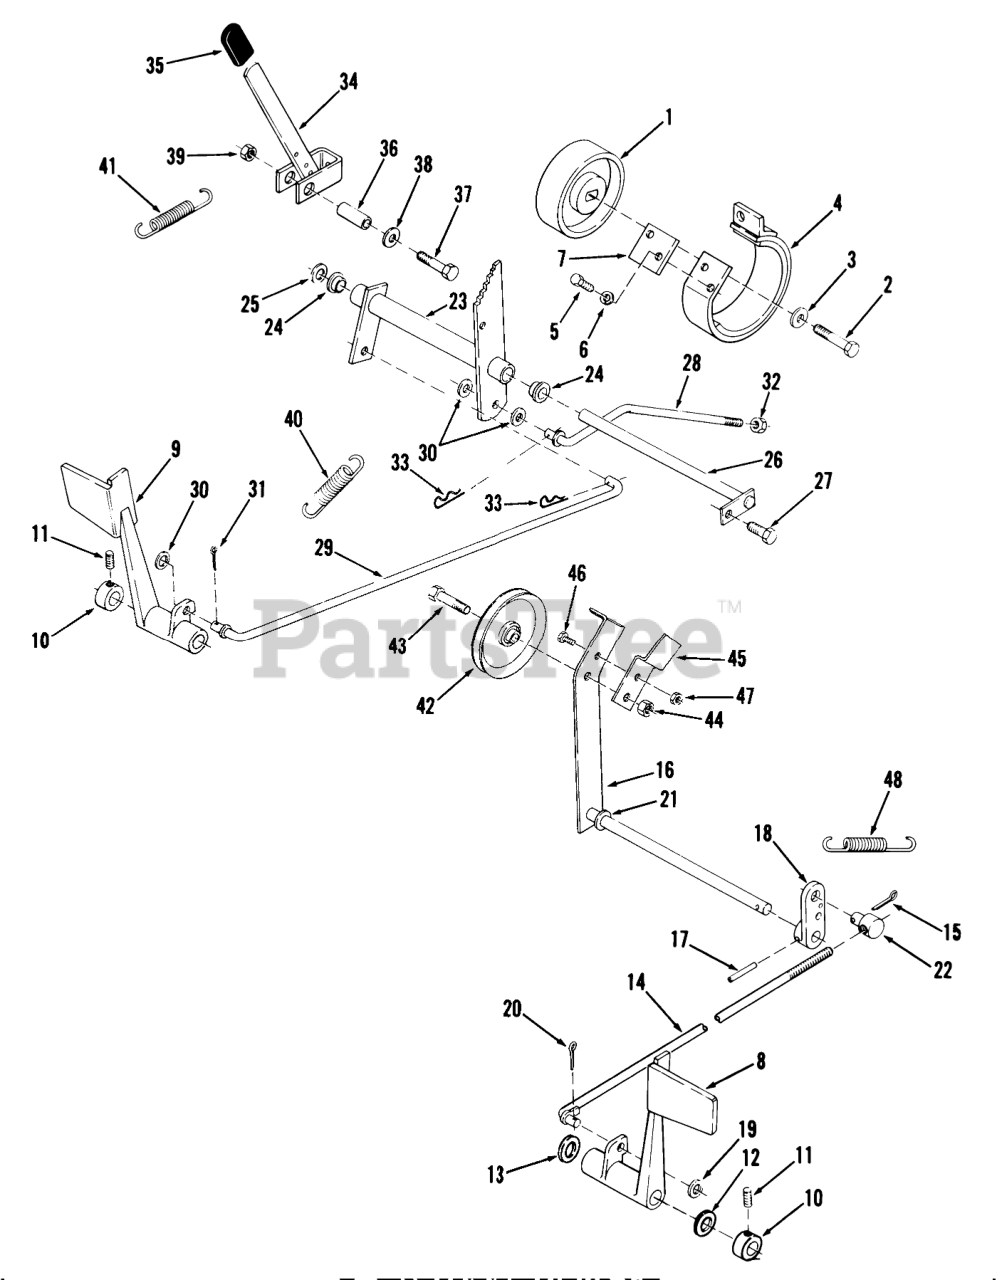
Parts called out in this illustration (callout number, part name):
1	DRUM-BRAKE
2	Bolt
3	WASHER
4	BRAKE BAND ASM
5	H H C S
6	Washer
7	Plate-Stop
8	Clutch Pedal
9	PEDAL-BRAKE R
10	Collar
11	SCREW-SET
12	WASHER-BOWED
13	WASHER
14	ROD AND GUIDE ASM
16	Clutch Idler Arm
17	PIN-SPIROL
18	Arm-Clutch Rod
19	WASHER-NYLON
20	Pop Rivet
21	SHIM-WASHER
22	TRUNNION
23	Bellcrank Assy
24	BUSHING-FLANGED
25	Washer
26	ROD ASM
27	SCREW
28	ROD-REAR BRAKE
30	WASHER-NYLON
31	Pop Rivet
32	NUT
33	Hairpin
34	ASSY-BRAKE LEVER WAB
35	GRIP
36	SPACER
37	Bolt
38	Washer
39	LOCKNUT-FLANGE
40	SPRING-BRAKE
41	SPRING-EXTENSION
42	PULLEY-IDLER
43	BOLT-SPECIAL HEX
44	Nut
45	SWITCH-ACTUATOR
46	H H C S
47	Nut
48	SPRING-CLUTCH
